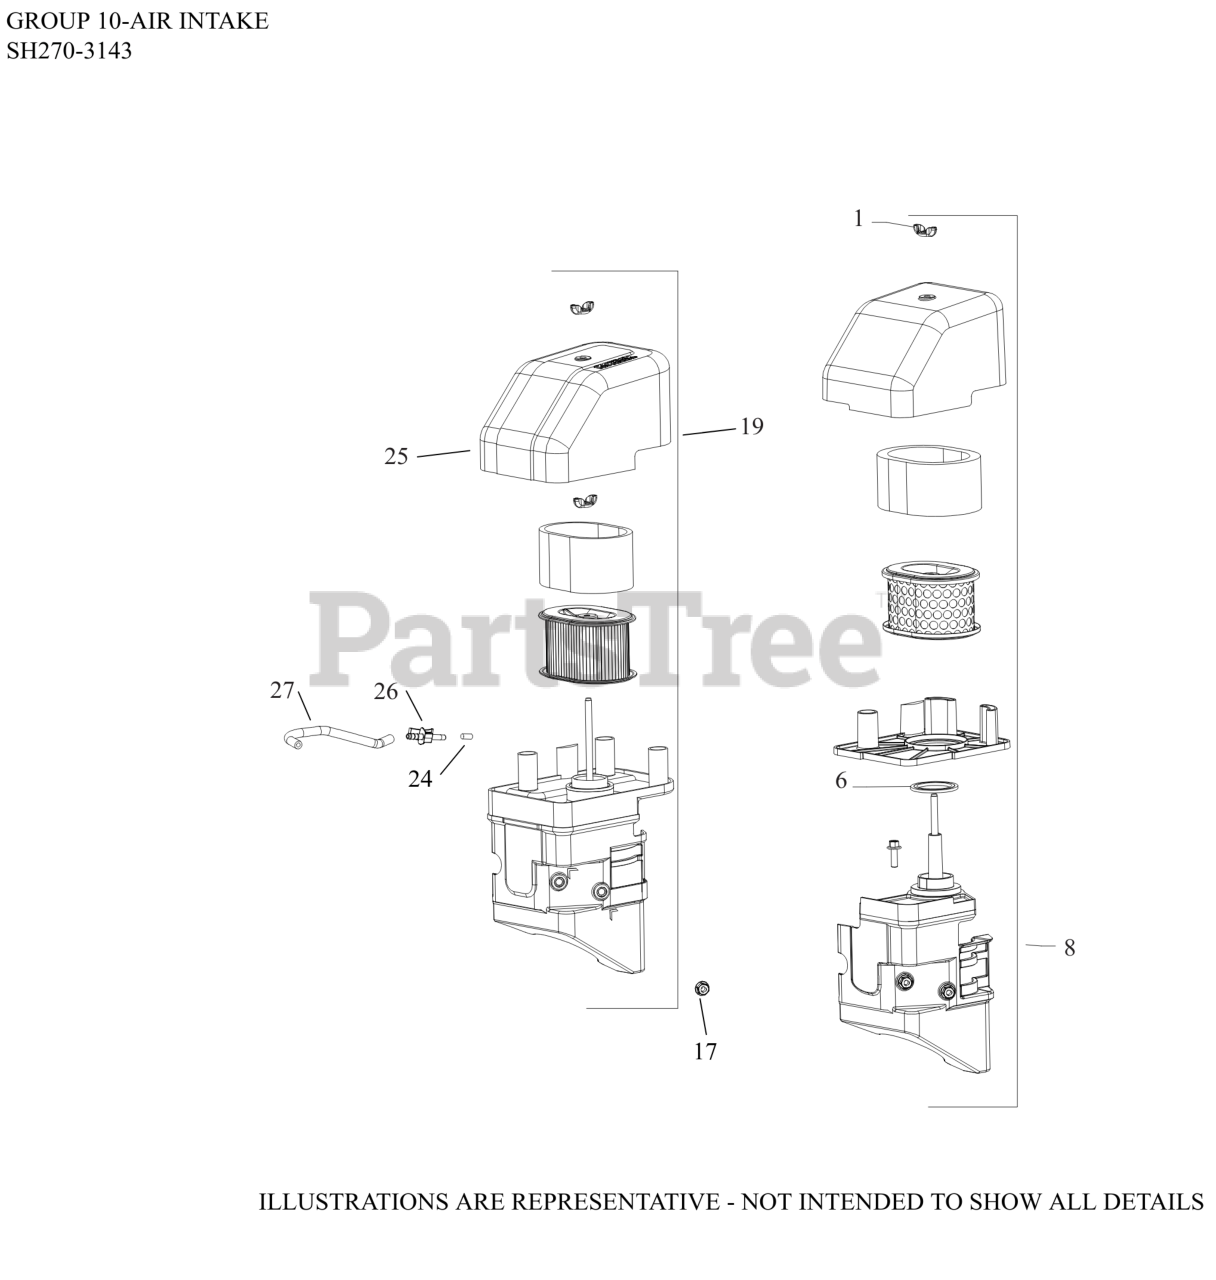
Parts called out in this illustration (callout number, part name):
1	NUT, WING
6	GASKET, AIR FILTER
17	NUT, HEX FLANGE LOCK (M6)
19	KIT, AIR CLEANER ASSEMBLY
20	ELEMENT, PRE-CLEANER
21	ELEMENT, AIR FILTER
24	CAP, MASKING (CKY)
25	COVER, AIR CLEANER ASSEMBLY
26	CONNECTOR, EVAPORATIVE
27	HOSE, EVAPORATIVE
